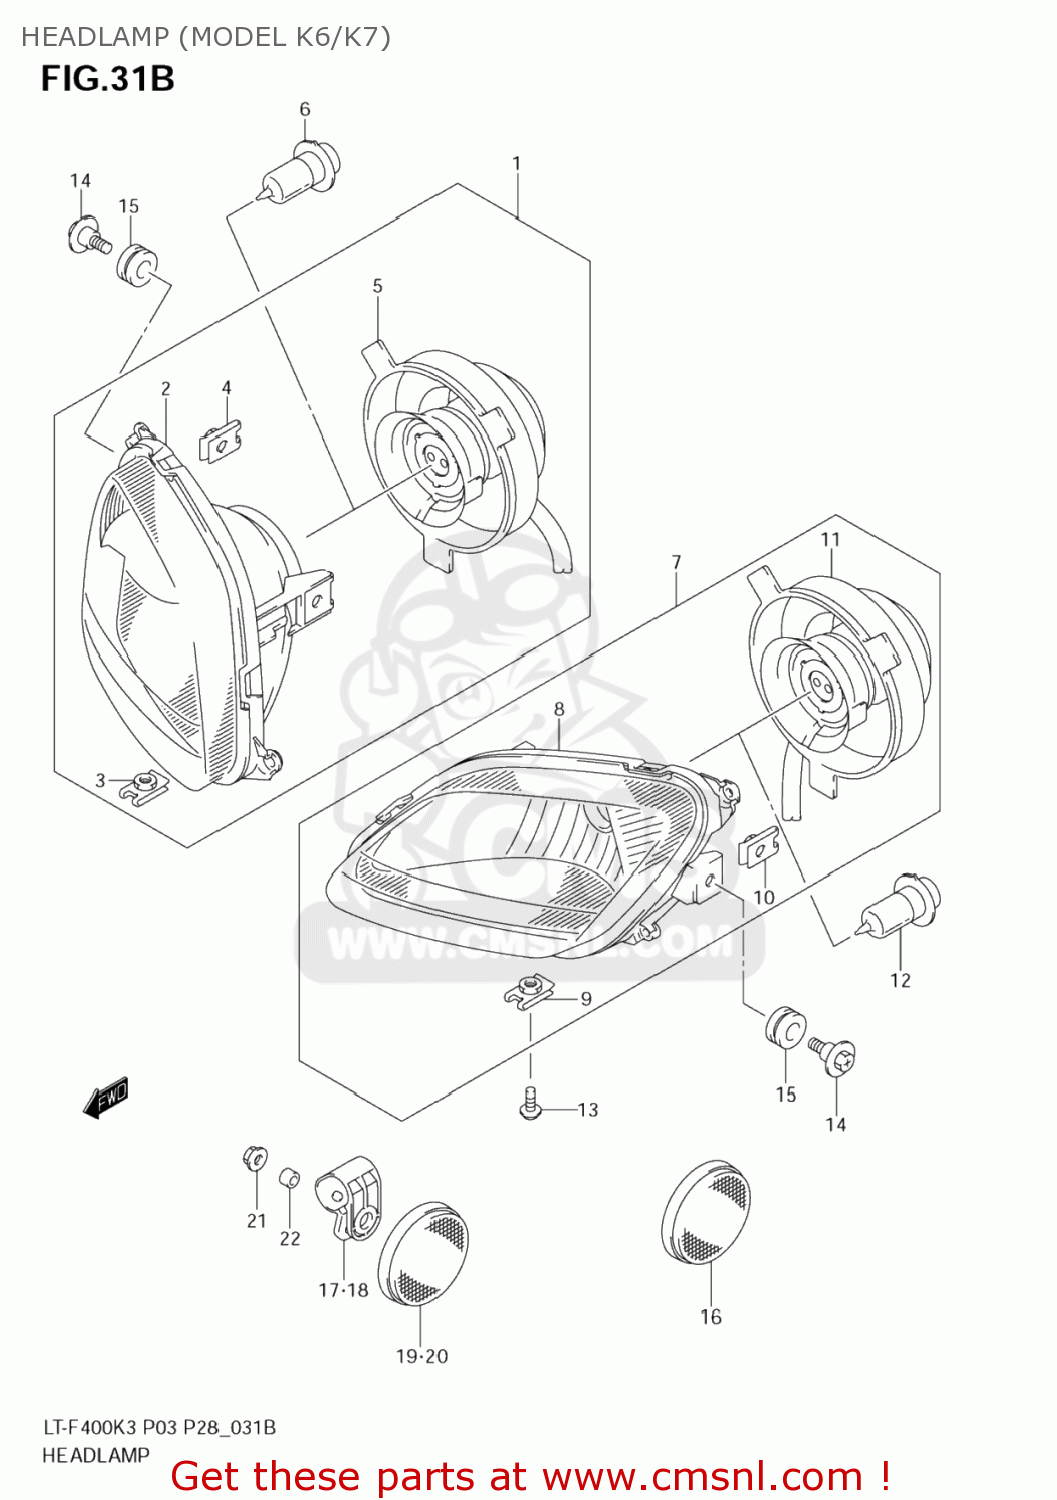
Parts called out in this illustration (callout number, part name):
1	HEADLAMP ASSY,R
2	UNIT,R
3	NUT(M5)
4	NUT(M6)
5	CORD ASSY,R
6	BULB(12V30/30W,STANLEY 03300A)
7	HEADLAMP ASSY,L
8	UNIT,L
9	NUT(M5)
10	NUT(M6)
11	CORD ASSY,L
12	BULB(12V30/30W,STANLEY 03300A)
13	SCREW(5X16)
14	SCREW(6X22.5)
15	CUSHION
16	REFLECTOR,REFLEX FR
17	BRACKET,FR SIDE REFLECTOR,R
18	BRACKET,FR SIDE REFLECTOR,R
19	REFLEX REFLECTOR
20	REFLEX REFLECTOR
21	NUT
22	SPACER(5.5X9.5X6.5)
